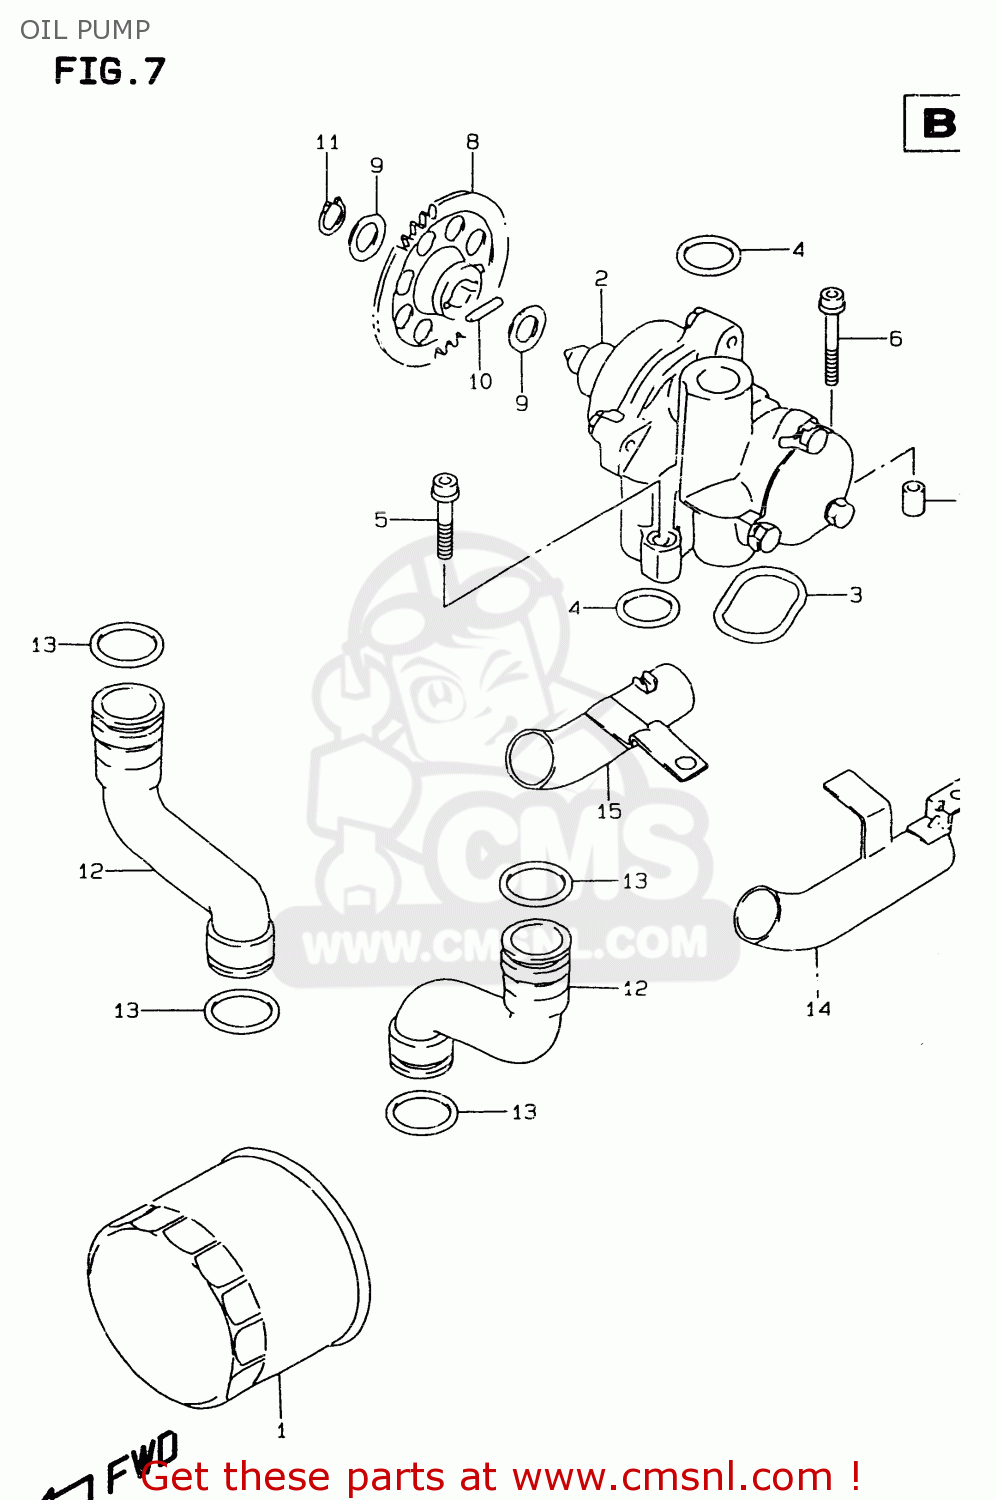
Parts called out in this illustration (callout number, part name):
1	FILTER ASSEMBLY,ENGINE OIL
2	PUMP ASSY,OIL
3	O RING,OIL PUMP
4	O RING(D:3.2,ID:17.8)
5	BOLT
6	BOLT
7	PIN
8	GEAR,OIL PUMP DRIVEN(NT:37)
9	SHIM
10	PIN(5X18)
11	CIRCLIP,12 MM
12	PIPE,OIL OUTLET
13	O RING(D:3.7,ID:21.7)
14	PIPE,OIL OUTLET UNDER,L
15	PIPE,OIL OUTLET UNDER,R
